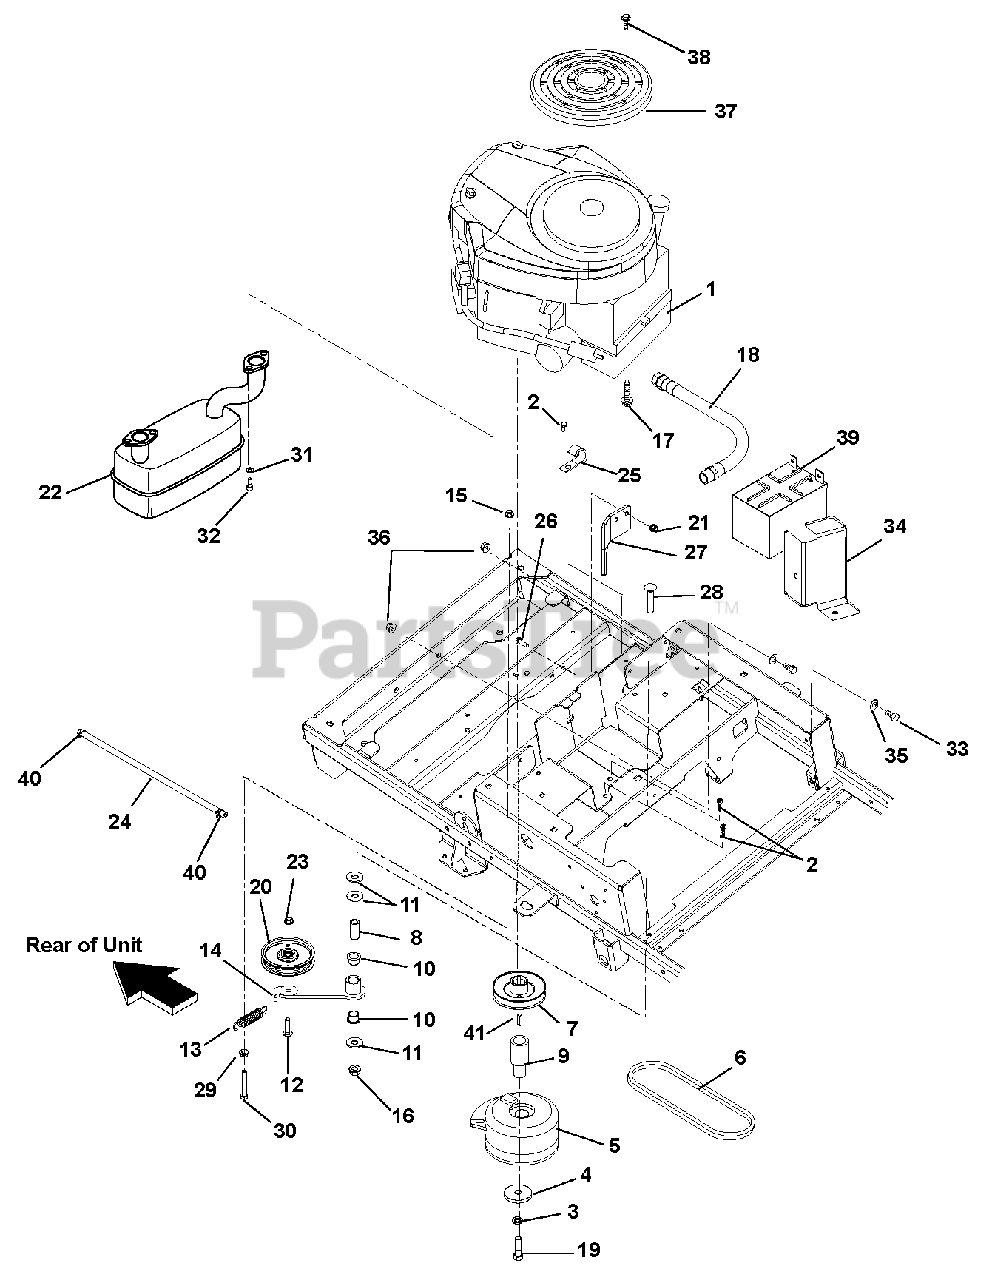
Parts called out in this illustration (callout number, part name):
1	Engine, 18HP V-Twin CE
2	Screw, Tapping .250-20 x .37 Hex Washer Head
3	Washer, Locking .44 x .109 Regular
4	Washer, Flat Steel .469 x 2.00 x .25
5	Clutch, XL
6	Belt, HA 62.50 Wrapped
7	Pulley, V 4.5 x 1.5 AB Section with Key
8	Bushing, Sleave .500 x .750 x .1.560
9	External, Crankshaft Lower
10	Bushing, Flange 0.75 x 0.875 x .625 x 1.125
11	Washer, Flat Steel .563 x 1.38 x .109
12	Bolt, Round Head Square Neck .38-16 x 1.50 Grade 5
13	Spring, Tension .105 x .812 x 3.88
14	Weldment, Ground Drive Idler Arm
15	Nut, 3/8-16 Flange Nyloc
16	Nut, Locking Top Flange .50-13
17	Screw, Tapping .38-16 x 1.00 Hex Washer Head
18	Hose Assembly, Oil Drive .38 x 11.5 OAL
19	Bolt, Hex .44-20 x 4.50 Grade 8
20	Assembly, 4" Idler
21	Nut, .31-18 Nyloc Flange
22	Muffler, Briggs & Stratton Twin
23	Nut, Locking Top Flange .38-16
24	Fuel Hose
26	Bolt, Hex .31-18 x 1.00 Grade 5
27	Clutch Stop
28	Bolt, Round Head Square Neck .50-13 x 2.50 Grade 5
29	Nut, Flange .375-16
30	Bolt, Hex .38-16 x 2.50 Grade 5
31	Washer, Locking .31 x .078 Regular
32	Screw, Cap .31-18 x .75
33	Bolt, Hex .25-20 x .75
34	Bracket, Battery Hold Down
35	Washer, Flat Steel .281 x .62 x .065
36	Nut, KEPS .250-20
37	Guard, Briggs & Stratton Engine
38	Screw, 8-16 x .87
39	Battery, 12V, 215 CCA, GEP
40	Clamp, Fuel Line
41	Key, Straight .25 x 2.0 x .25
